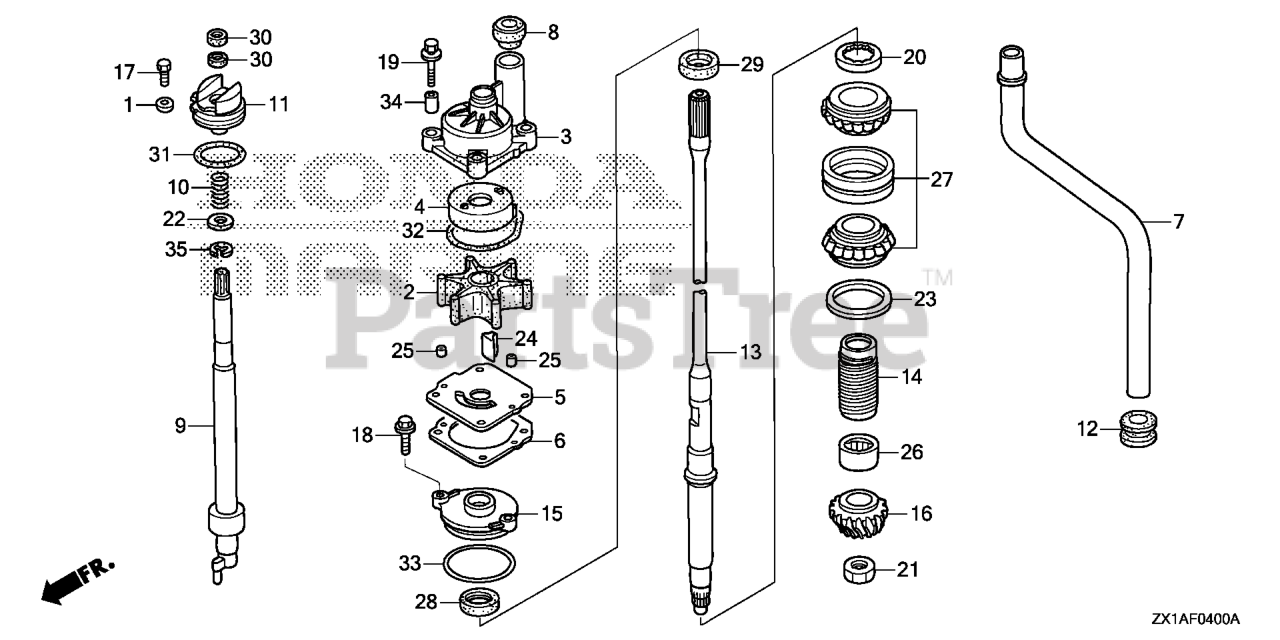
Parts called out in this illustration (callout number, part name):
1	WASHER, PIVOT
2	IMPELLER, PUMP
3	HOUSING, IMPELLER
4	LINER, PUMP
5	COVER, IMPELLER
6	GASKET B, IMPELLER
7	TUBE, WATER (XL)
8	RING, WATER TUBE SEAL
9	ROD, SHIFT
10	SPRING, SHIFT ROD
11	HOLDER, SHIFT ROD
12	GROMMET, EXTENSION CASE
13	SHAFT, VERTICAL (XL)
14	SLINGER, OIL
15	HOUSING, WATER SEAL
16	GEAR, PINION
17	BOLT, HEX. (6X12) Use up to Frame SN 1005248.
18	BOLT, FLANGE (6X20) (ENGINE NO.)
19	BOLT-WASHER (8X40)
20	NUT, LOCK (64MM)
21	NUT, HEX. (18MM)
22	WASHER, PLAIN (12MM)
23	SHIM A, GEAR (0.10)
23	SHIM B, GEAR (0.15)
23	SHIM C, GEAR (0.30)
23	SHIM D, GEAR (0.50)
24	KEY, WOODRUFF
25	PIN, DOWEL (6X10)
26	BEARING, NEEDLE (28.575X44.45X31.75)
27	BEARING, TAPER ROLLER (30X62X40)
28	SEAL, WATER (23X36X8)
29	SEAL, WATER (23X36X6)
30	SEAL, WATER (12X21X6)
31	O-RING (55.6X3.5)
32	O-RING, WATER PUMP
33	O-RING (58.5X3.5)
34	COLLAR, DISTANCE
35	E-RING (10MM)
